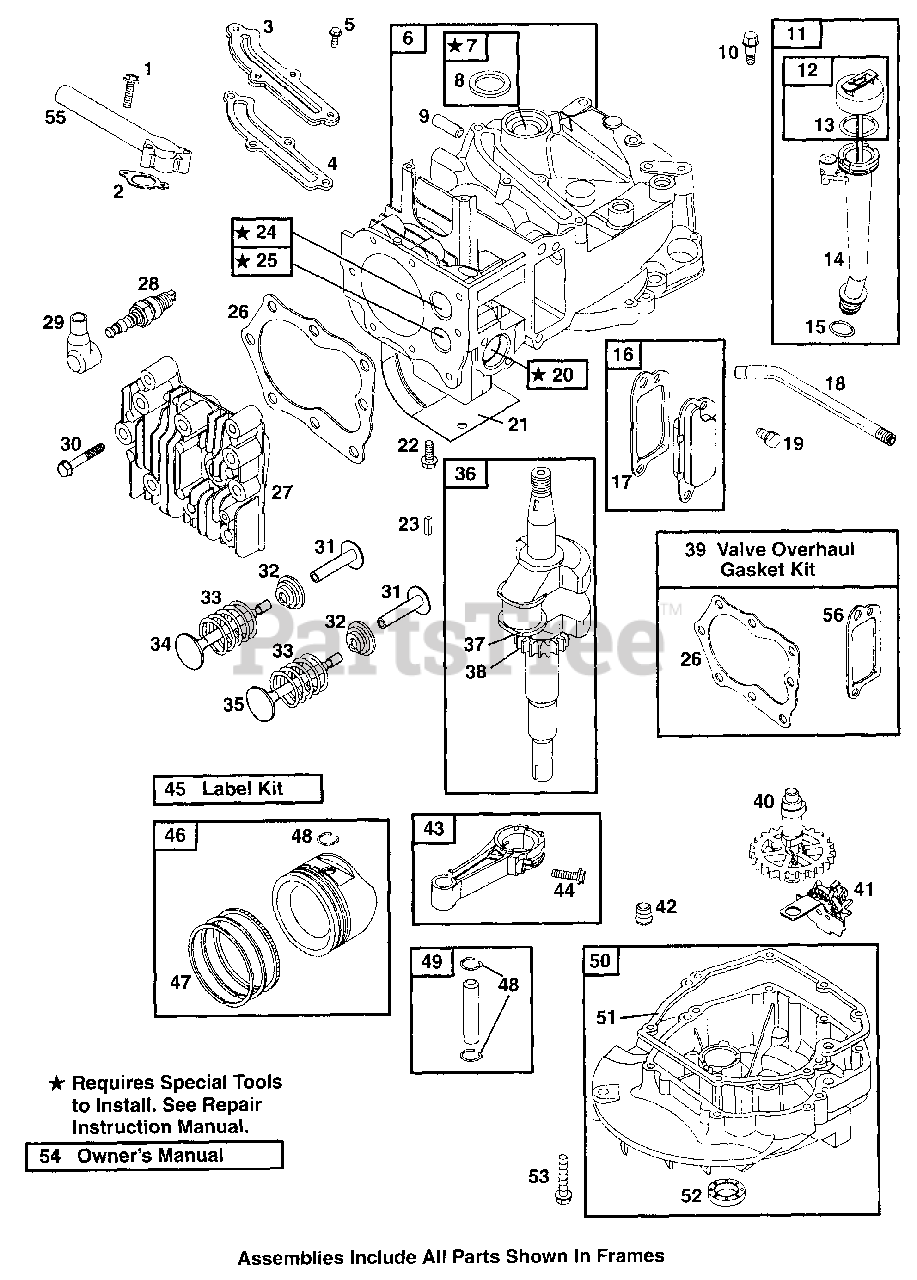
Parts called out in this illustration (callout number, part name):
1	Screw (Intake Manifold)
2	Intake Gasket
3	Breather Passage Cover
4	Breather Passage Gasket
5	Screw (Breather Passage Cover)
6	Cylinder Assembly
7	Bushing/Seal Kit
8	Oil Seal
9	Locating Pin
10	Screw (Dipstick Tube)
11	Dipstick/Tube Assembly
12	Dipstick
13	Dipstick/Tube Seal
14	Oil Fill Tube
15	Dipstick Tube Seal
16	Breather Assembly
17	Breather Gasket
18	Breather Tube
19	Screw (Breather Assembly)
20	Guide Bushing (Intake Valve)
21	Cylinder Shield
22	Screw (Cylinder Shield)
23	Flywheel Key
24	Valve Seat (Intake)
25	Valve Seat (Exhaust)
26	Cylinder Head Gasket
27	Cylinder Head
28	Spark Plug
29	Sparkplug Boot
30	Screw (Cylinder Head)
31	Valve Tappet
32	Valve Retainer
33	Valve Spring (Intake)
34	Intake Valve
35	Exhaust Valve
36	Crankshaft
37	Timing Key
38	Timing Gear
39	Valve Gasket Set
41	Governor/Oil Slinger
42	Oil Drain Plug
43	Connecting Rod
44	Screw (Connecting Rod)
46	Piston Assembly (Standard)
47	Ring Set (Standard)
48	Piston Pin Lock
49	Piston Pin
50	Engine Sump
51	Crankcase Gasket
52	Oil Seal
53	Screw (Engine Sump)
54	Owner's Manual
55	Intake Manifold
56	Breather Gasket
